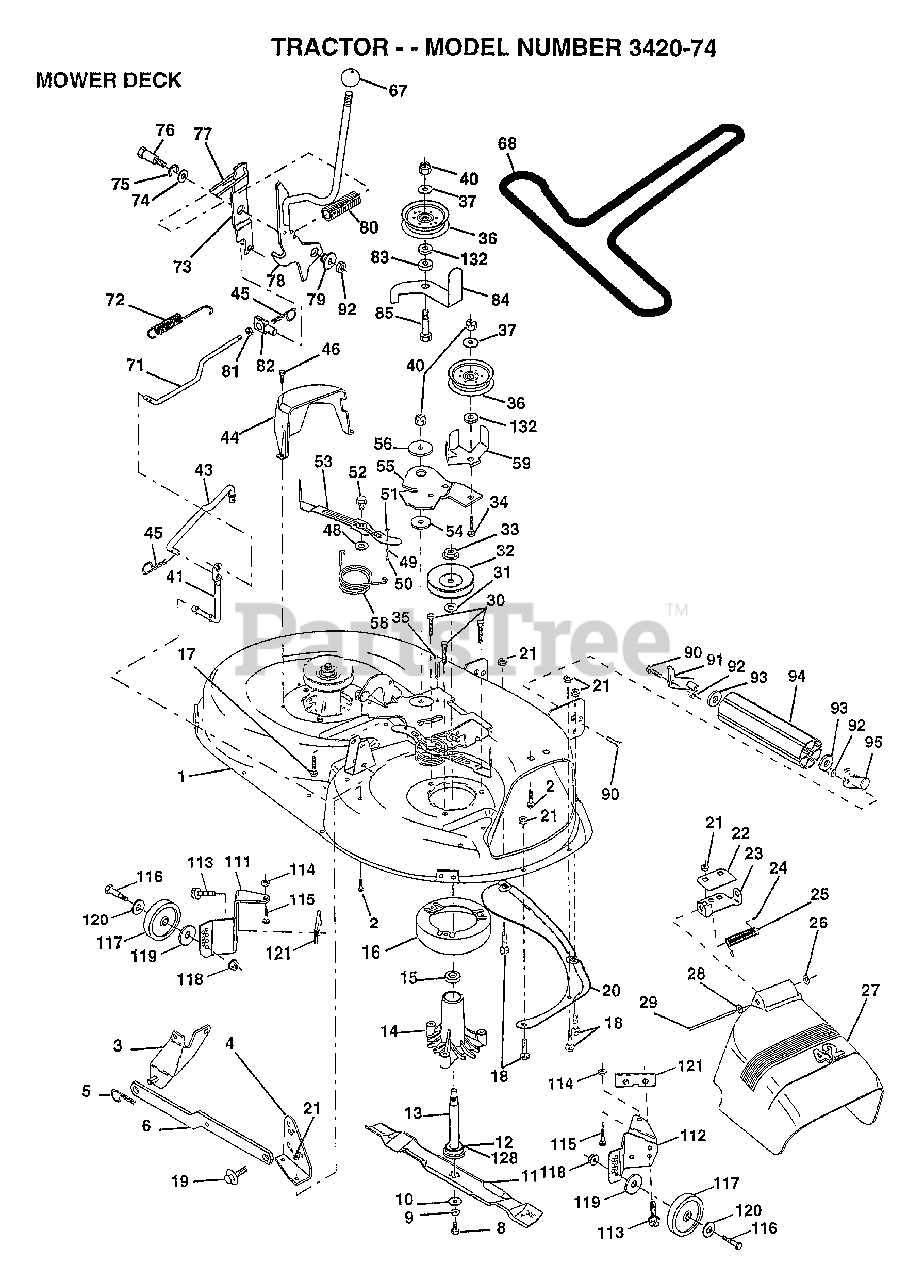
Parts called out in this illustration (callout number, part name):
1	DECK.WELD.42.
2	BOLT
3	BRKT ASM SWAY BAR
4	BRKT DECK SW BAR
8	BLADE BOLT
10	WASHER.HARD.BLADE
11	"BLADE.42"" HIPERF"
12	BEARING.BALL
14	HSG ASM MANDREL
15	BEARING
16	STRIPPER RND MWR
17	BOLT RDHD 3/8-16
18	BOLT
19	BOLT SHD 5/16-18
22	STIFFENER BRKT
23	DEFLECTOR BRKT
24	CAP-SLEEVE LT
25	SPRING TORSION
26	NUT PUSH M
27	DEFLECTOR.SHIELD
28	WASHER
29	HINGE ROD
31	WASHER
32	PULLEY.MANDREL.42
34	BOLT
35	XMAS TREE FASTNER
36	FLAT IDLER PULLEY
37	WASHER
41	PIVOT ROD
43	ROD CLUTCH W/NIBS
44	GUARD MAND LH BLK
45	RETAINER M
46	SCREW.1/4-20X5/8
48	HARD SMALL WASHER
49	ROLLER ASM-CAM
50	SHOULDER BOLT
51	LOCKNUT
52	BOLT.SHLD.5/16-18
54	HARDENED WASHER
55	ARM-IDLER
56	SPACER RETAINER
58	SPRING TORSN BRAK
59	GUARD IDLER TUV
68	BELT.V.T-PATH
71	ROD CLUTCH 38/42
72	RETURN SPRING
73	CLUTCH ARM SECOND
74	WASHER
75	RING
76	SHOULDER BOLT
77	SPRING KEEPER
78	LOWER ASM CLUTCH PRIMARY YP
79	BUSHING
80	SPRING.CLUTCH.MWR
81	NUT
82	TRUNION ADJ
83	WASHER
84	"KEEPER-BELT,FIXED"
85	BOLT RDHD 3/8-16
90	BOLT
92	NUT
93	WASHER
111	BRACKET.GWHL.LH.
112	BRACKET.GWHL.RH.
113	SCREW
116	BOLT M
117	WHEEL.GAGE.BLK.PL
118	LOCKNUT
119	WASHER
120	WASHER
121	BRACKET.EXTRD.GWL
128	WASHER.FELT.
132	WASHER GT
